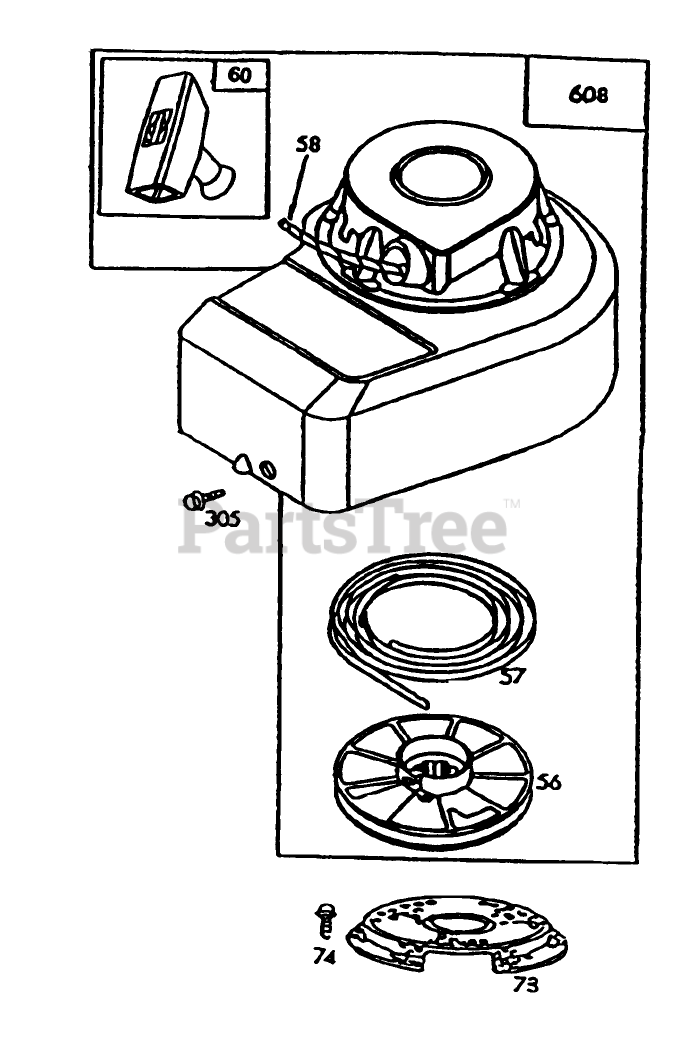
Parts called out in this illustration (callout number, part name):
56	Pully-Starter
57	Spring-Rewind
58	Insert-Starter Grip
60	Grip-Starter Rope
73	Screw-Sem
74	Screw-Sem
305	Screw-Blo. Hsg. Mtg.
608	Sorter Assy.-Rewind
